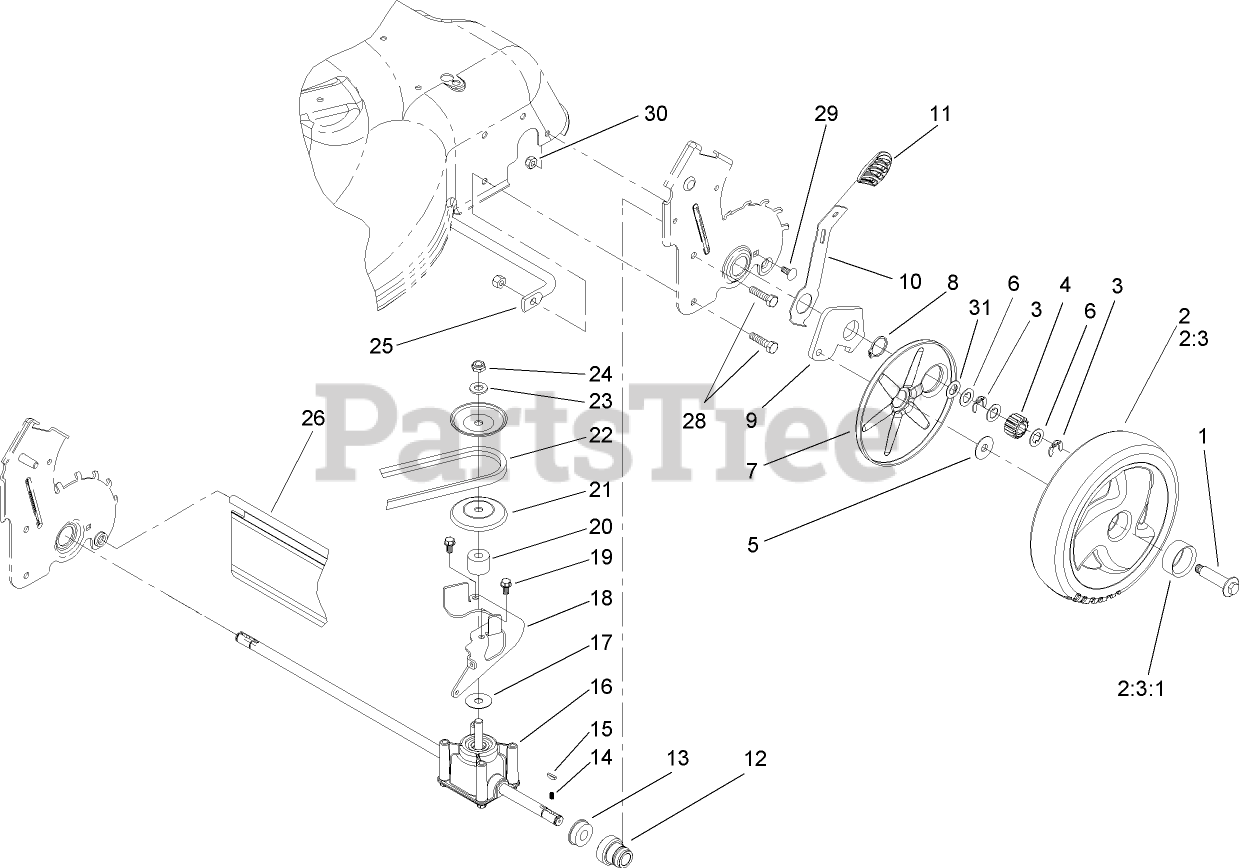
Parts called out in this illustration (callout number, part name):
1	BOLT-SHOULDER
2	WHEEL GEAR ASM
2:3	Loose Parts Package
2:3:1	BUSHING
3	RING-RETAINING,CLIP
4	GEAR-PINION, 15T
5	WASHER-STEPPED
6	WASHER-THRUST
8	RING-RETAINING
9	ARM-PIVOT, REAR (LH)
10	ARM-SPRING
11	KNOB-LEVER, HOC
12	RETAINER-BEARING, HOC
13	BEARING-BALL
14	SPRING-COMPRESSION
16	TRANSMISSION ASM
17	WASHER-PLAIN
19	SCREW-HWH
20	SPACER
21	PULLEY-HALF
22	BELT-V
23	WASHER-FLAT
24	NUT-HEX
25	BRACE-PLATE, HOC
28	SCREW-HH
29	SCREW-CARR
30	NUT-LOCK, NI
31	WASHER-PLAIN
